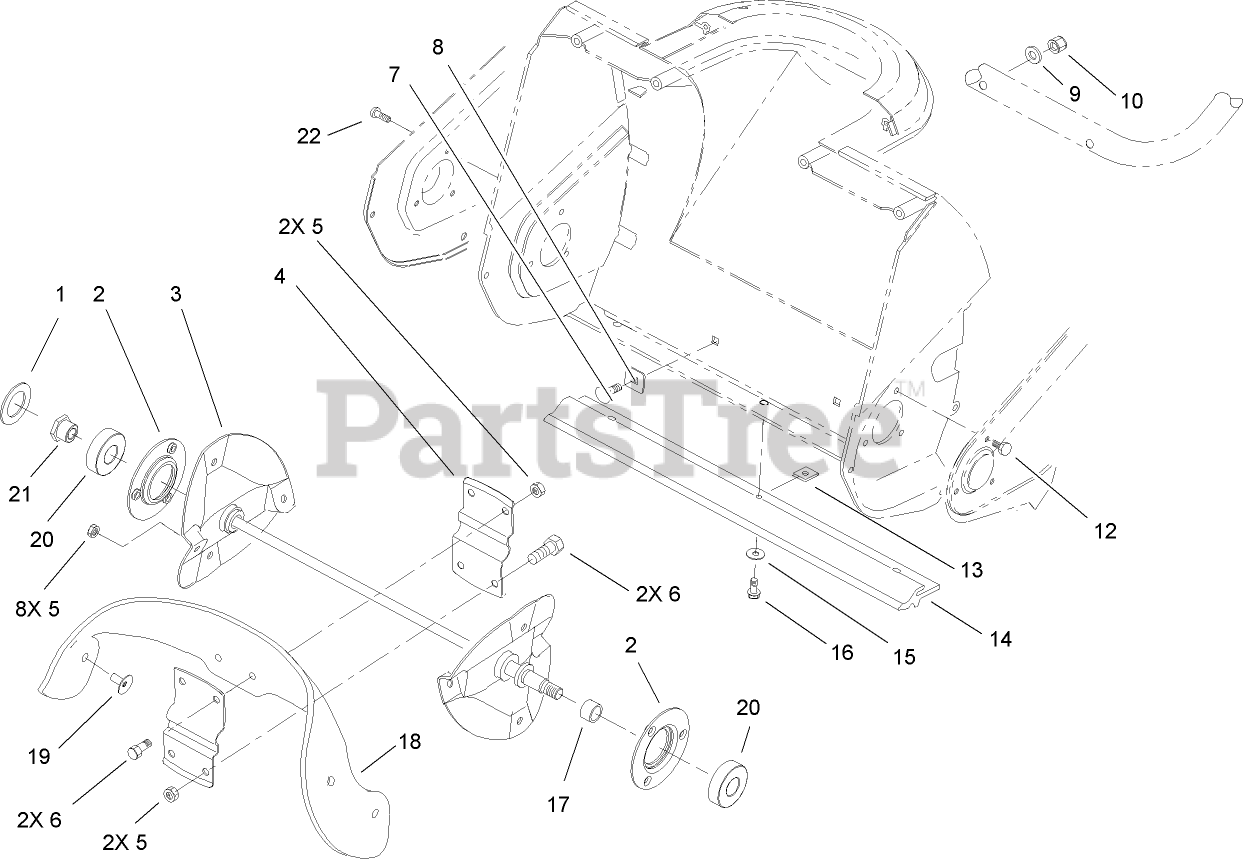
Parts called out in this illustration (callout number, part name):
1	WASHER-RUBBER
2	FLANGE-BEARING
3	ROTOR SHAFT ASM
4	SUPPORT-ROTOR
5	NUT-LOCK, NI
6	SCREW-HHF
7	SCREW-CARR
8	WASHER-SQUARE
9	WASHER
10	NUT-LOCK, NI
12	SCREW-HH, TAPTITE
13	NUT-CLIP, U
14	SCRAPER
15	WASHER-FLAT
16	SCREW-HWHTF
17	SPACER
18	BLADE-ROTOR
19	SCREW
22	SCREW-HWH
